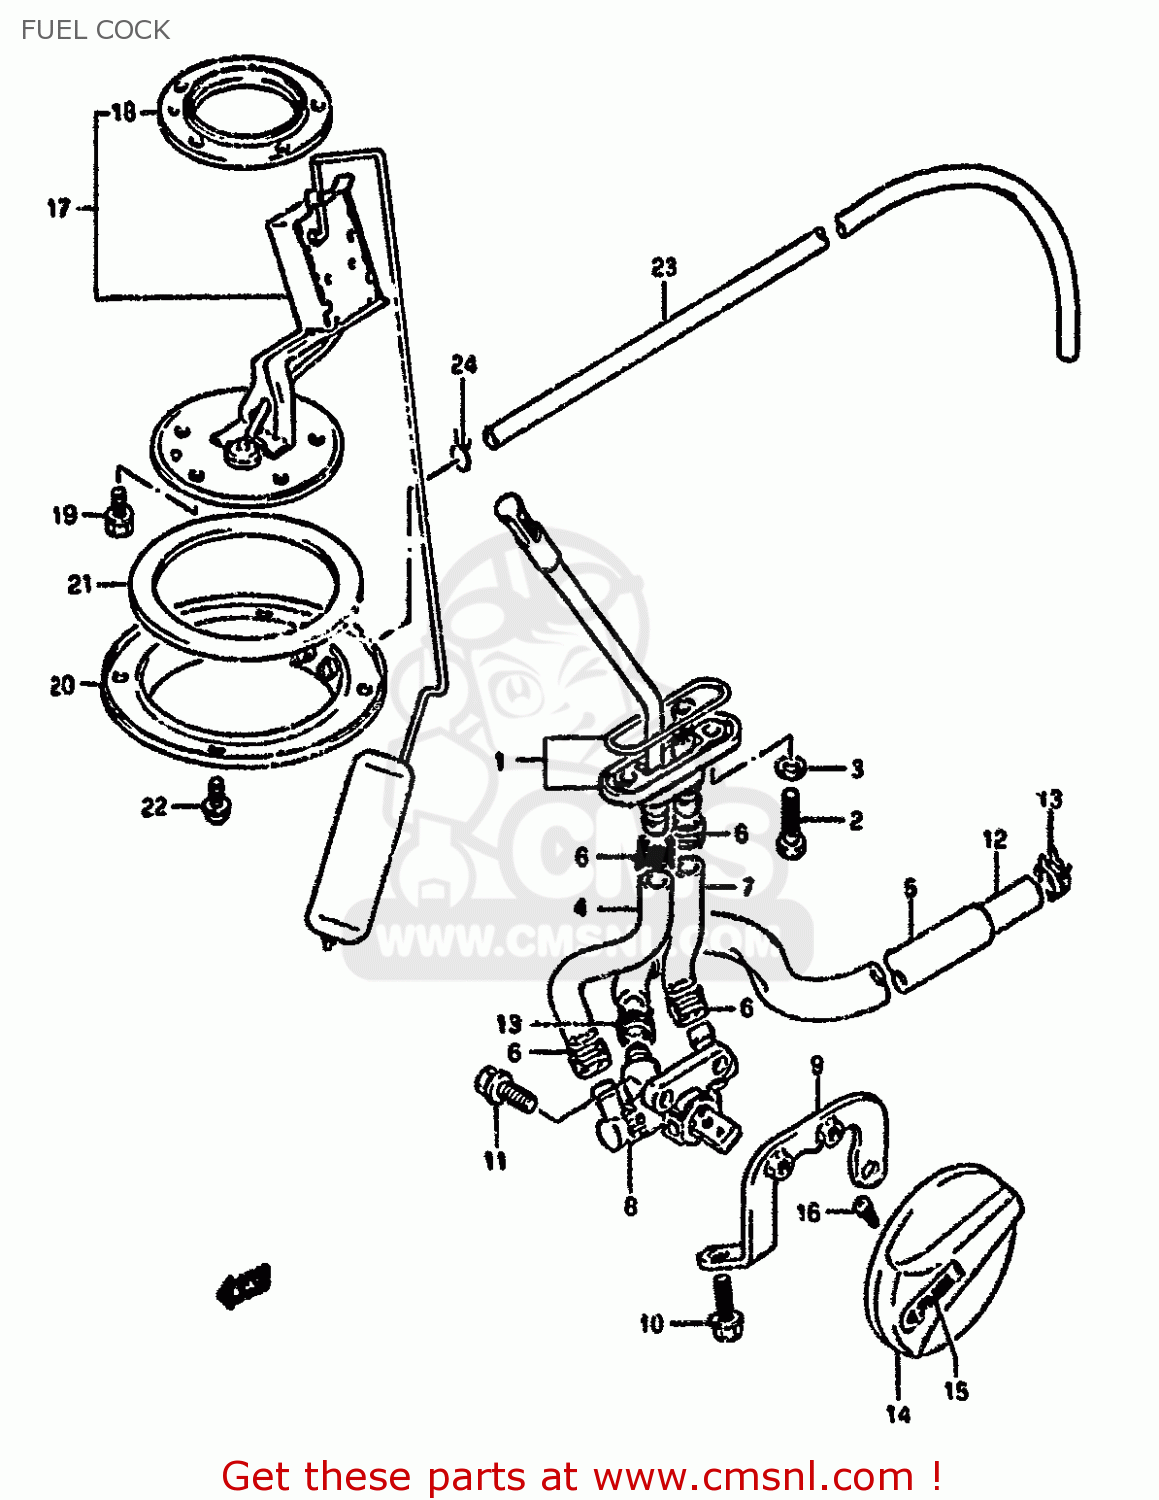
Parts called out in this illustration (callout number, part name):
1	FILTER UNIT,FUEL
2	BOLT(6X20)
3	GASKET(6.4X11.5X0.8) (NAS)
4	HOSE,FUEL ON
5	PROTECTOR(14.5X15.5X600)
6	CLAMP
7	HOSE,FUEL RESERVE
8	COCK ASSEMBLY,FUEL
9	PLATE,FUEL COCK
10	SCREW
11	BOLT
12	HOSE (7X12X600)
13	CLAMP
14	LEVER,FUEL COCK
15	LABEL,FUEL COCK LEVER
16	SCREW
17	GAUGE ASSEMBLY,FUEL LEVEL
18	GASKET,FUEL LEVEL GAUGE (NAS)
19	BOLT
20	PLATE,FUEL DRAIN
21	GASKET,FUEL DRAIN PLATE (NAS)
22	SUZUKI PART
23	HOSE
24	CLIP
